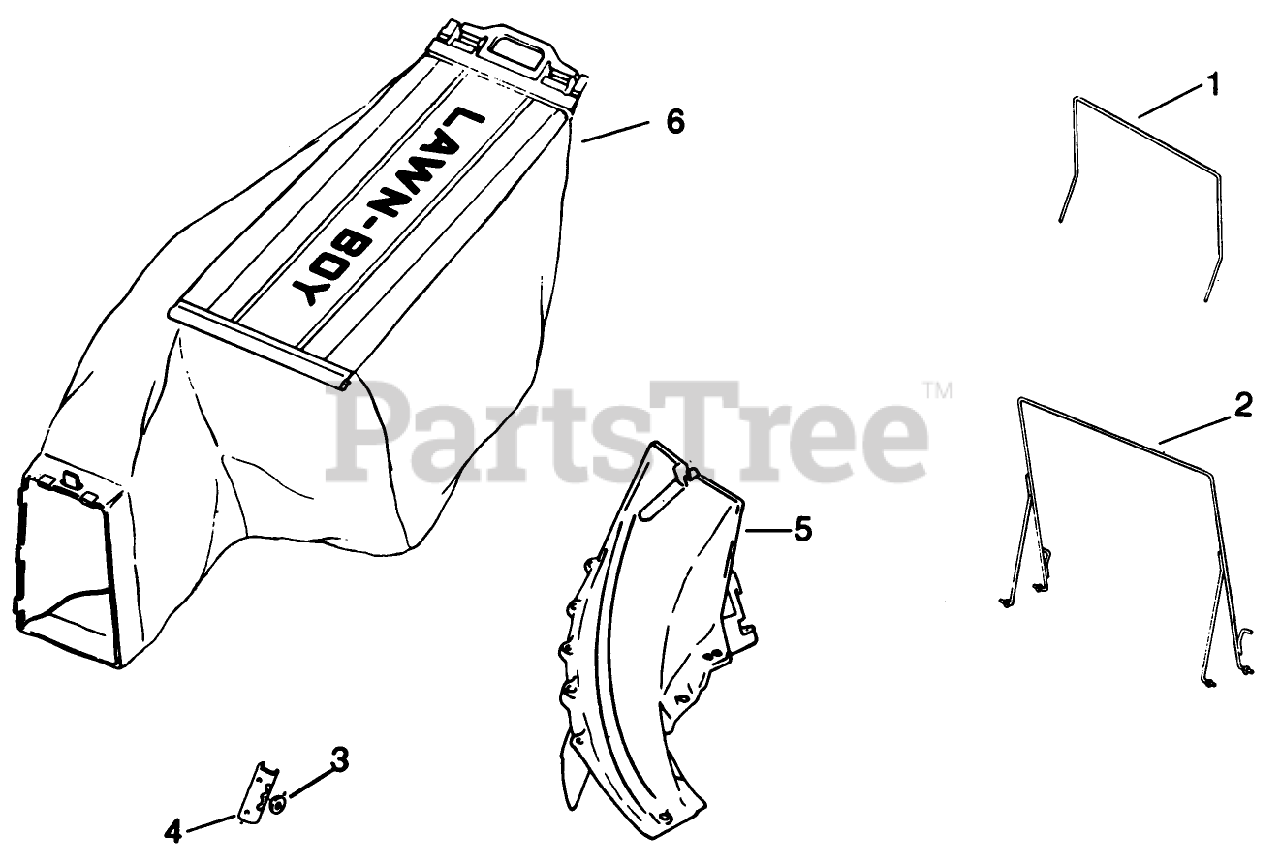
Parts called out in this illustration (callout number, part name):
1	HANGER
3	WASHER-CURVED
4	BRACKET R/B 613462
